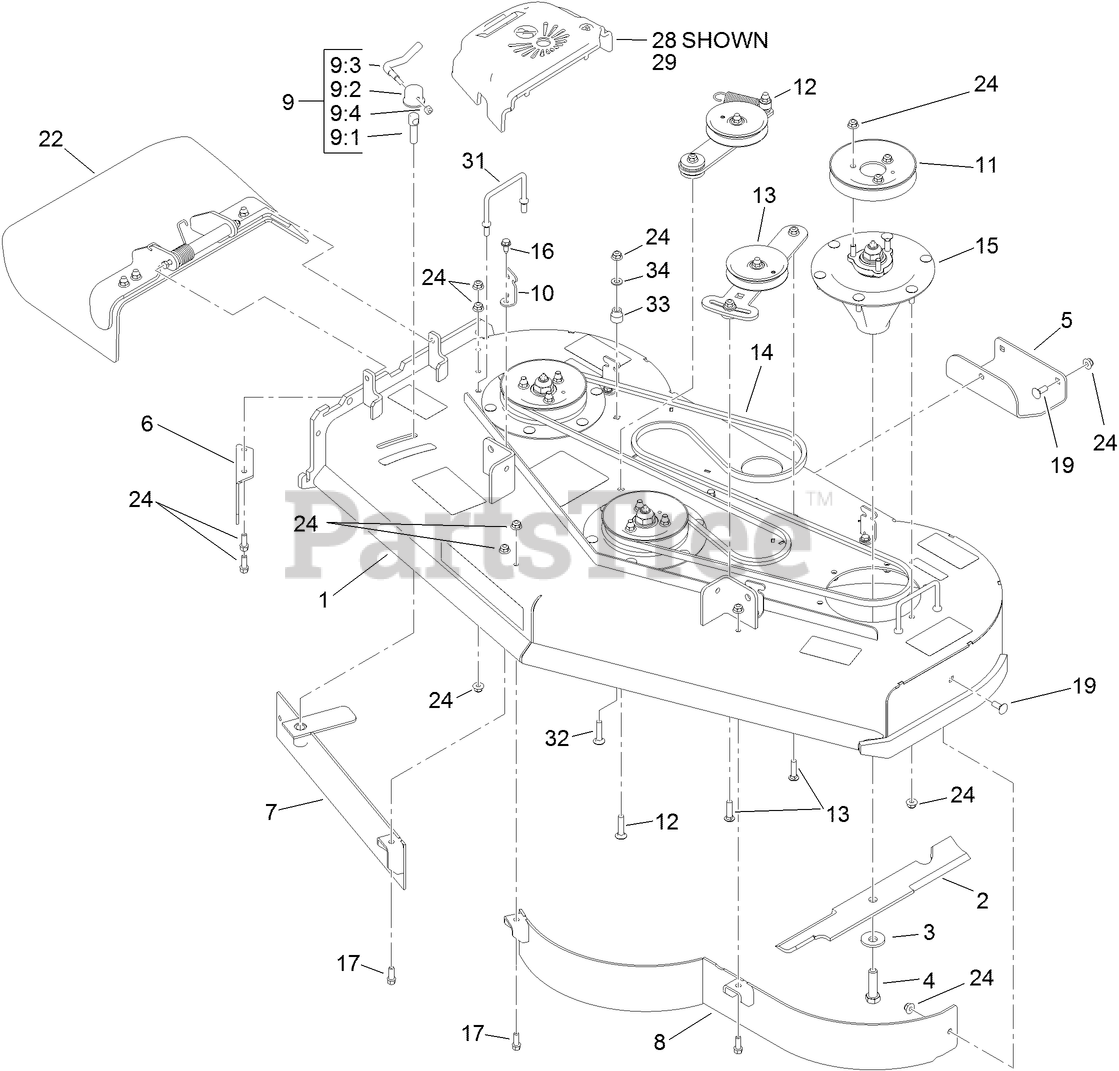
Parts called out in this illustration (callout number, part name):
1	DECK ASM
2	BLADE-18IN, HI FLOW
3	Washer-Blade Bolt, Heavy
4	SCREW-BLADE
6	BAFFLE-DISCHARGE
7	BAFFLE ASM
8	BAFFLE-52 INCH
9	LEVER ASM
9:1	Screw-Lock
9:2	CAP-LOCK
9:3	Lever-Lock
9:4	NUT-LOCK, NI
10	BRACKET-COVER
11	PULLEY
12	IDLER ARM ASM
13	IDLER ADJUST ASM
14	BELT-V
15	SPINDLE ASM
16	SCREW-HWHTF
17	SCREW-HWH
19	BOLT-CARR
22	DEFLECTOR ASM
24	NUT-HF, NI
28	COVER-BELT, RH
29	COVER-BELT
31	WIREFORM-COVER
32	SCREW-CARR
33	BUSHING-IDLER
34	WASHER-FLAT
